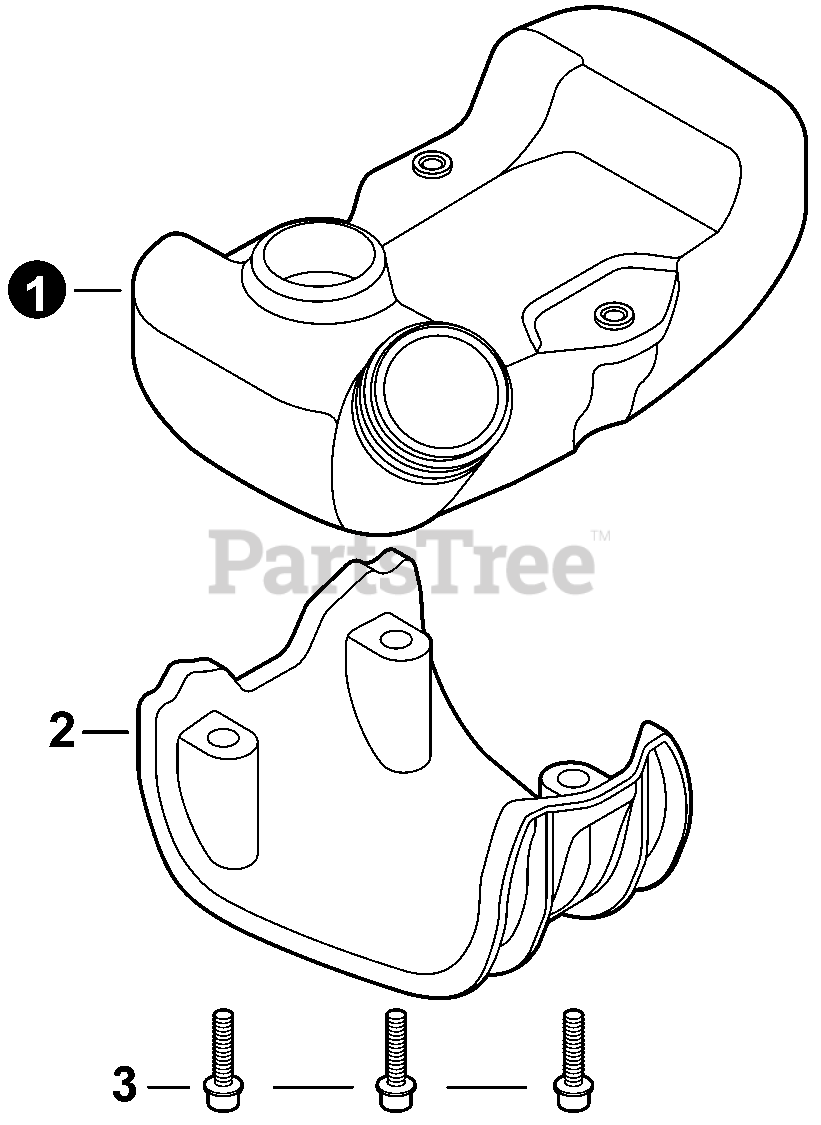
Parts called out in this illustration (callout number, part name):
1	TANK, FUEL
2	GUARD, FUEL TANK
3	BOLT 5×20
